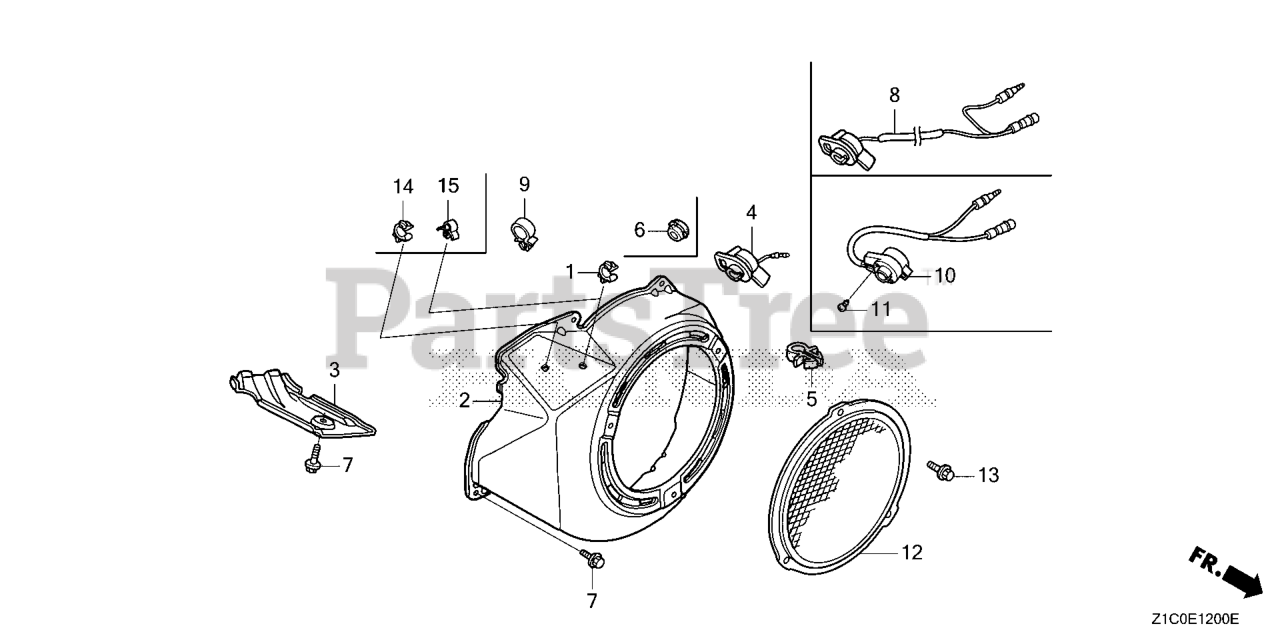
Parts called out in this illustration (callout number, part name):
1	CLIP, TUBE
2	COVER, FAN *R280* (POWER RED)
6	GROMMET, DRAIN HOLE
7	BOLT, FLANGE (6X12) (CT200)
